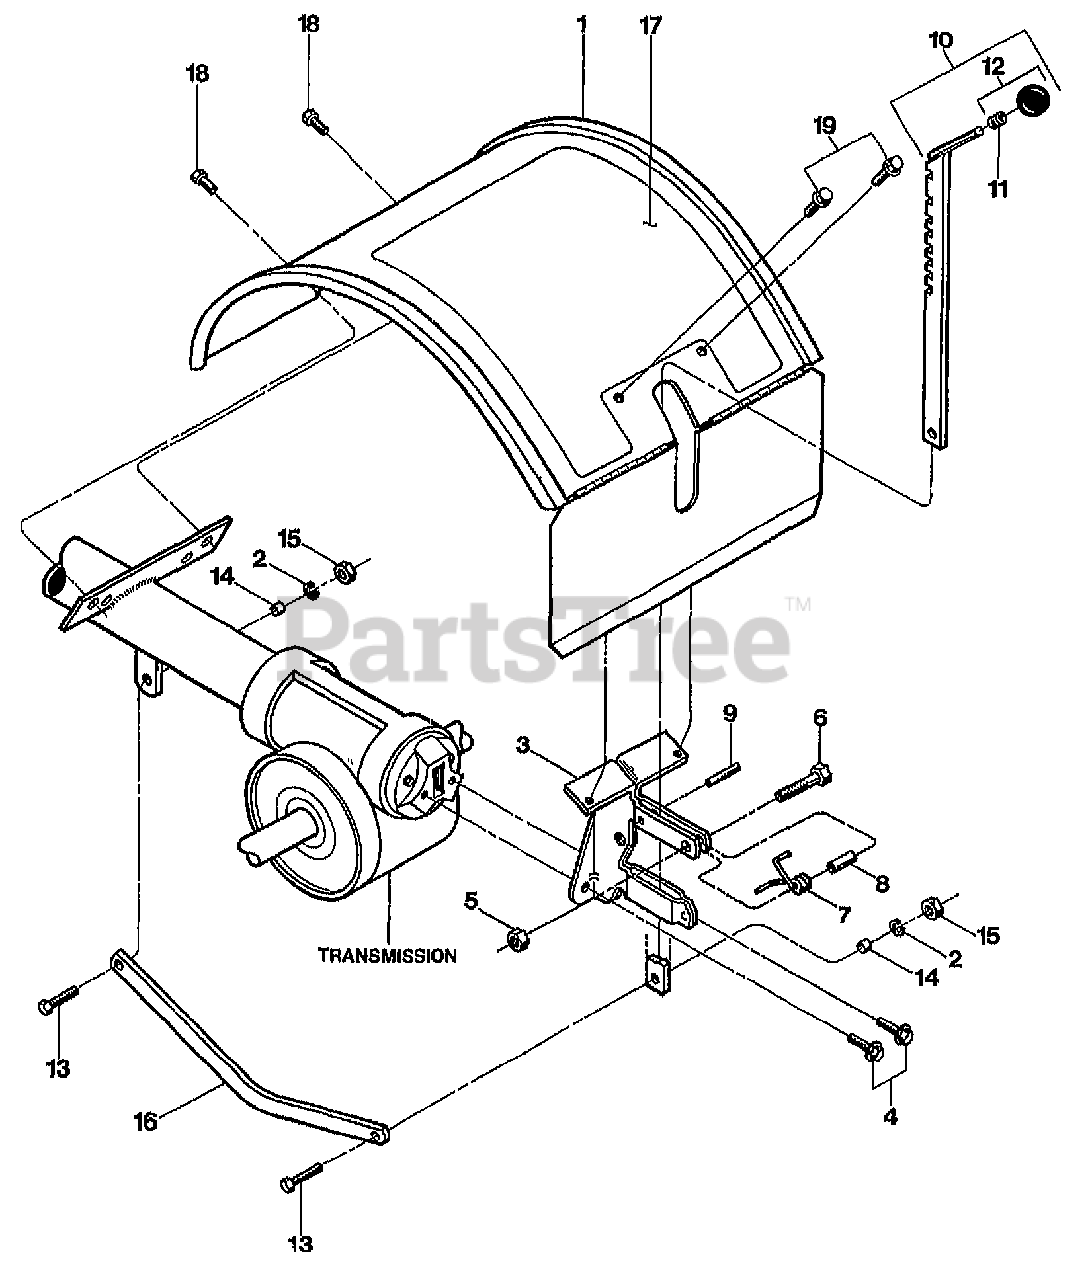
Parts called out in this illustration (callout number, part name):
1	HOOD W/DECALS JR 0PC (INCL. 17)
1	HOOD W/DECALS JUNIOR (INCL. 17)
2	WASHER-LK .375 @ DEPL
3	BRKT W/ROLL PIN (9308) (INCL.9)
4	SCR-HFLK 5/16-18X.62 G5ZP
5	NUT-LK 1/4-20
6	SCR-HH 1/4-20X1.0
7	SPRING-TORSION
8	SPACER-.250X.343X.375
9	PIN-ROLL .25 X 1
10	DEPTH REGULATOR W/KNOB (INCL. 11-12)
11	RING-TOLERANCE .5325 ID
12	KNOB-CONTROL (INCL.11)
13	SCR-HH 3/8-16X1.25
14	BUSHING-.5X.375X.3
15	NUT-HEX 3/8-16 ZP
16	DRAG BAR-BENT (DEPTH REGULATOR)
17	DECAL-HOOD JR
17	DECAL-HOOD INST JUNIOR
18	SCR-HWH 5/16-18 X .5 STH
19	SCR-HWH 1/4-20 X .5 STH
